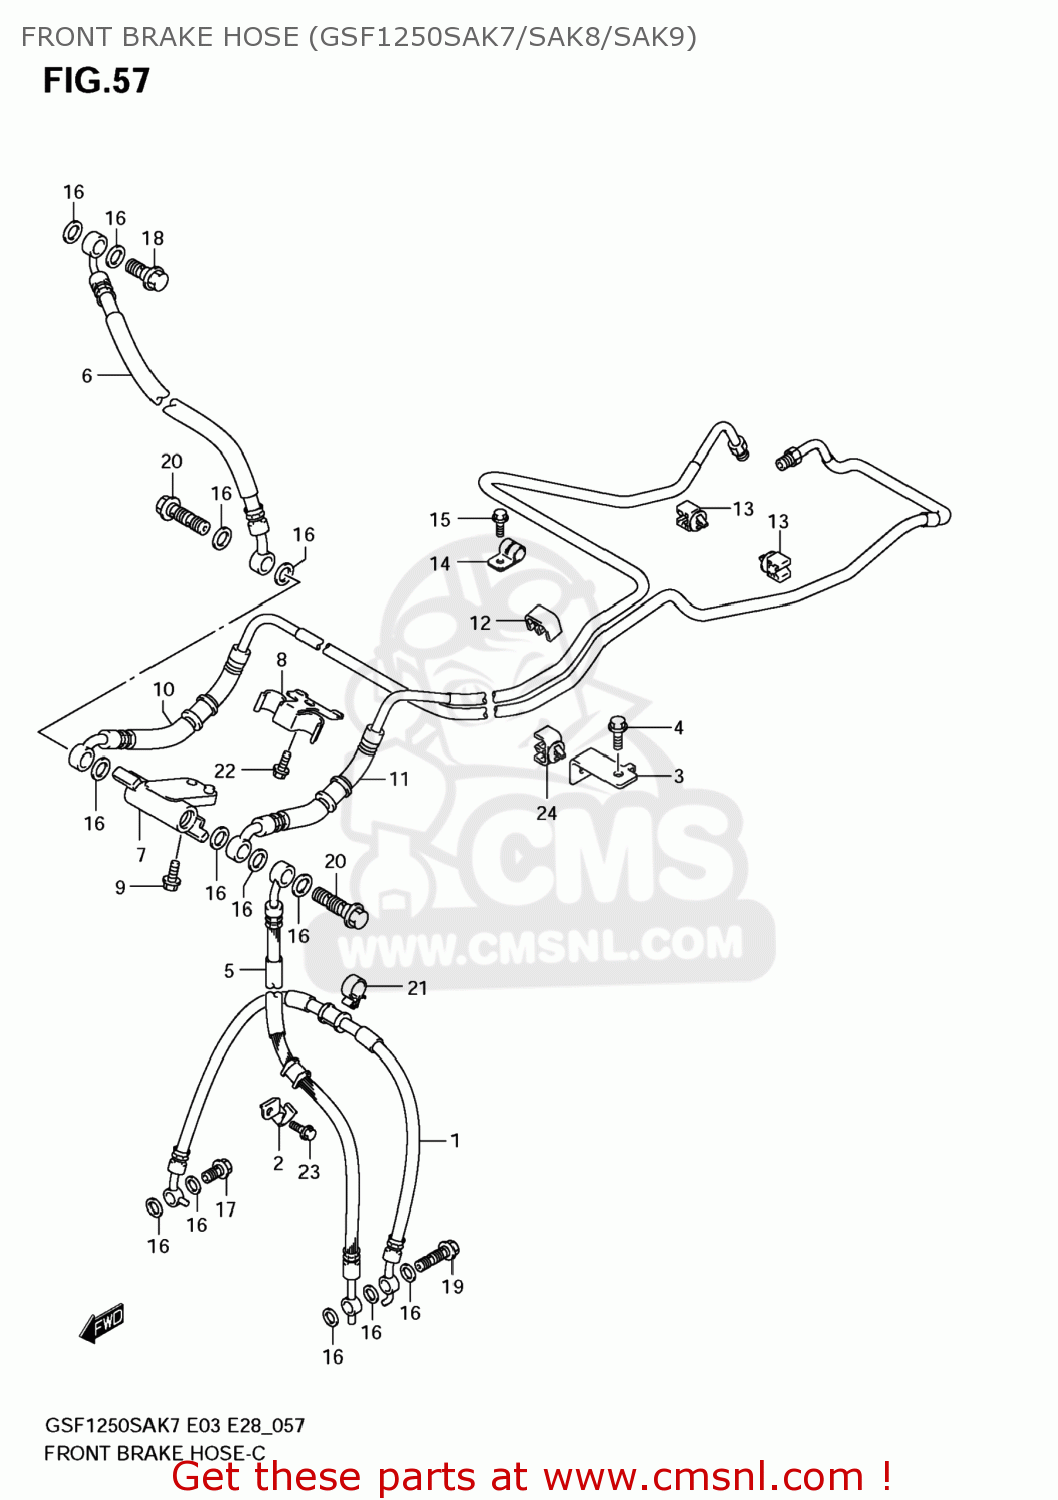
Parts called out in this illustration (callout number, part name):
1	HOSE,FR BRAKE NO.2
2	CLAMP,FR BRAKE HOSE NO.2,L
3	CLAMP,FR BRAKE HOSE ASSY
4	BOLT
5	HOSE,FR BRAKE NO.2,L
6	HOSE,FR BRAKE NO.1
7	JOINT,FR BRAKE HOSE
8	CLAMP,FR BRAKE JOINT HOSE
9	BOLT
10	HOSE ASSY,FR BRAKE NO.1
11	HOSE ASSY,FR BRAKE NO.2
12	CLAMP
13	CLAMP,BRAKE PIPE AXLE NO.2
14	CLAMP
15	BOLT
16	WASHER(10X15X1.5)
17	BOLT UNION
18	BOLT UNION
19	BOLT UNION
20	BOLT UNION
21	CLAMP
22	BOLT
23	BOLT
24	CLAMP
